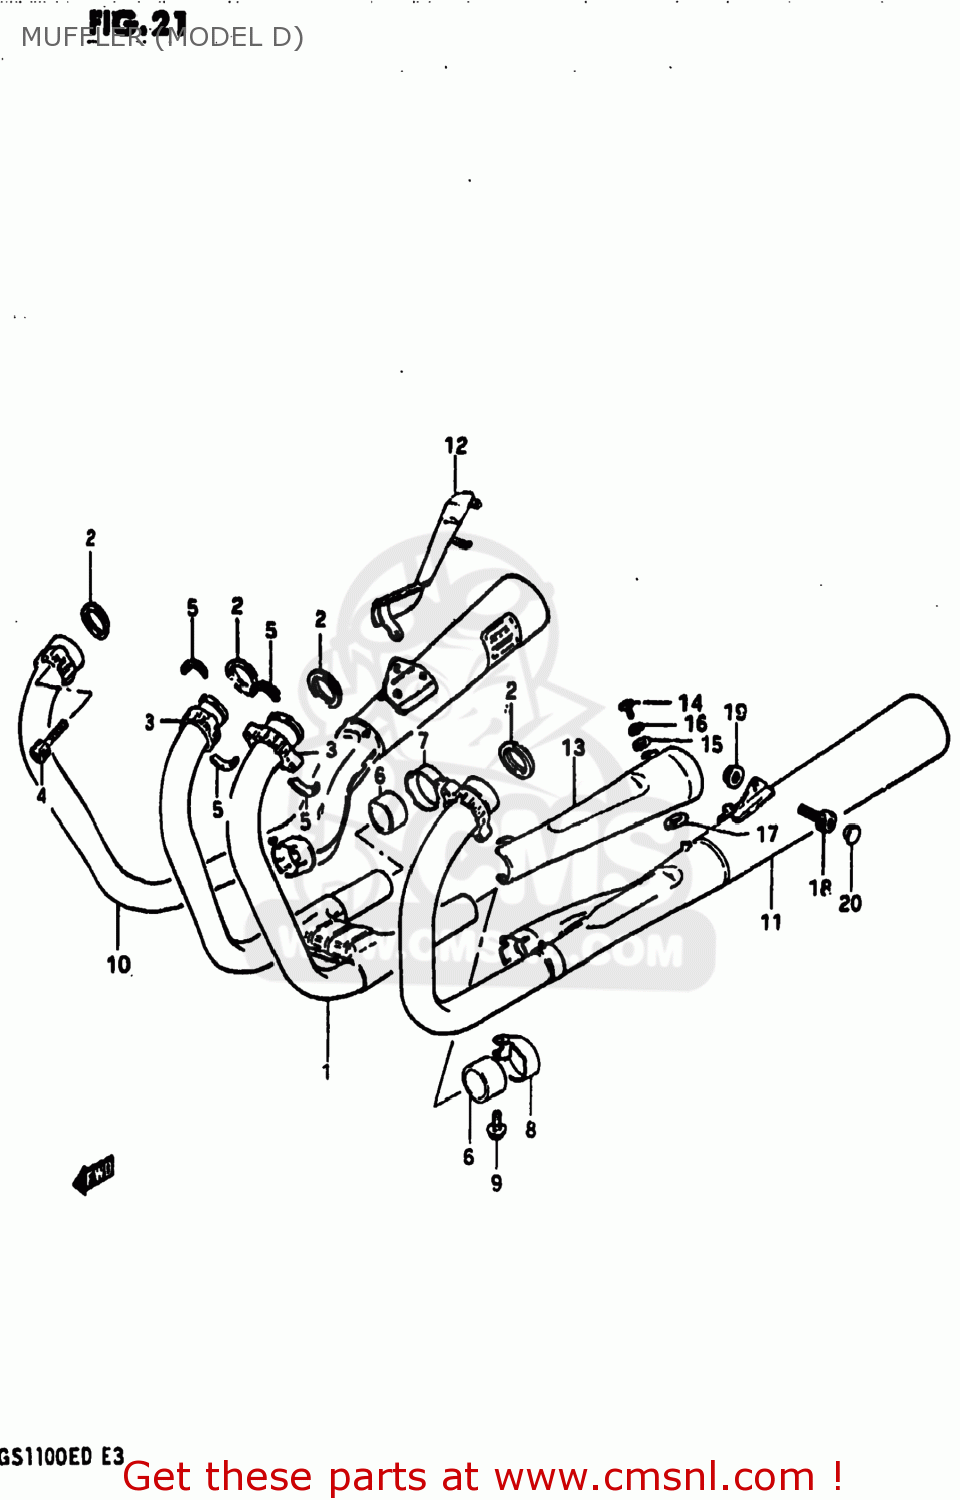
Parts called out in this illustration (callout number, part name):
1	PIPE,EXHAUST
2	GASKET,EXHAUST PIPE (NAS)
3	CLAMP,EXHAUST PIPE
4	BOLT
5	PLATE,EXHAUST
6	CONNECTOR,MUFFLER
7	CLAMP,MUFFLER CONNECTOR,R
8	CLAMP,MUFFLER CONNECTOR,L
9	BOLT
10	MUFFLER ASSEMBLY,RIGHT
11	MUFFLER ASSEMBLY
12	COVER,MUFFLER
13	COVER,MUFFLER
14	SCREW
15	WASHER,5MM
16	LOCK WASHER
17	GASKET 6.2X12X1.5 (MCA)
18	BOLT
19	NUT
20	CAP
